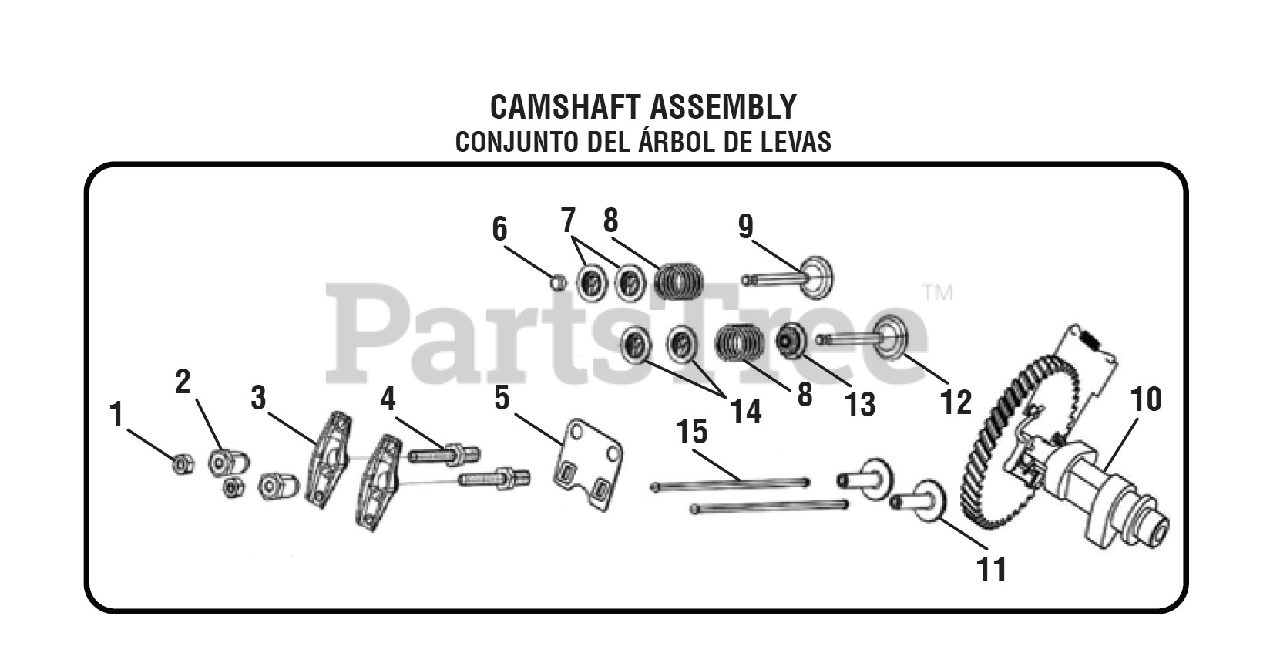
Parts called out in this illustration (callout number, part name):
1	Valve Lock Nut
2	Valve Adjusting Nut
3	Valve Rocker
4	Valve Adjusting Bolt
5	Lifter Stop Plate Assembly
6	Valve Rotator
7	Valve Lock Clip
8	Valve Spring
9	Exhaust Valve
10	Camshaft Assembly
11	Valve Tappet
12	Intake Valve
13	Seal Guide
14	Valve Spring Seat
15	Valve Lifter
